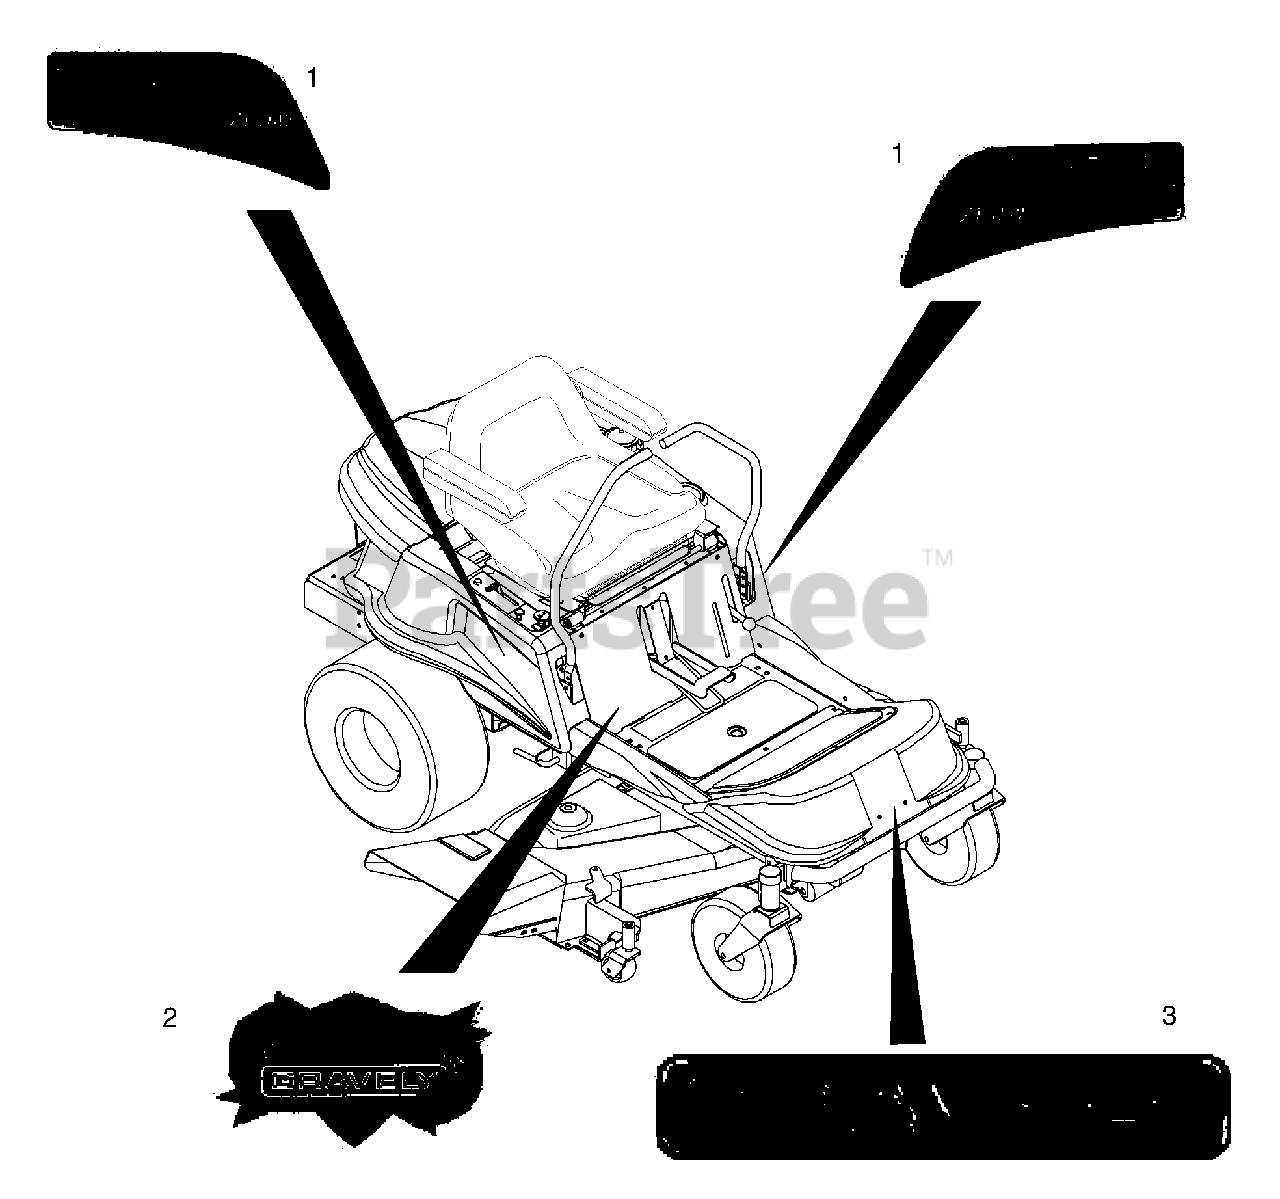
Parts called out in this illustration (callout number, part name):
1	Decal, Set ZT 1742
1	Decal, Set ZT 2048
2	Decal, Zero Turn
3	Decal, Gravely Logo
